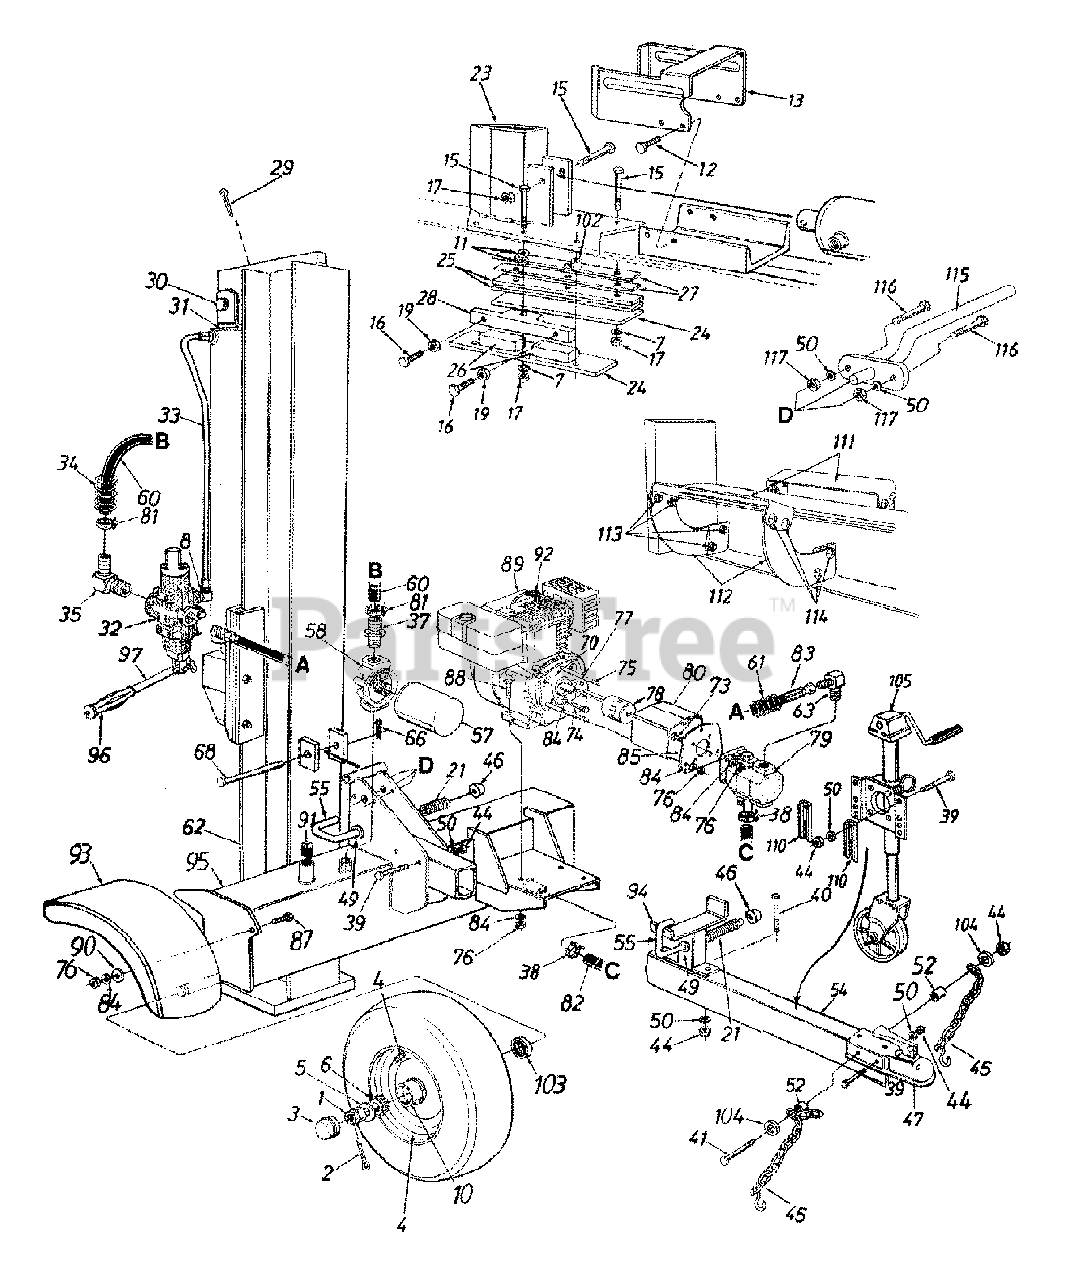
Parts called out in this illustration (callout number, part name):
1	Slotted Nut 3/4-16 Thd.
2	Cotter Pin 5/32" Dia.
3	Hub Cap
4	Wheel Ass'y. Comp.
5	Fl-Wash. .76" I.D. x 1.5" O.D.
6	Bearing Cone
7	L-Wash. 1/2" I.D.
8	90° Solid Male Adapter
10	Bearing Cup
11	Fl-Wash. .531" I.D. x .94" O.D.
12	Hex Cap Scr. 3/8-16 x 1" Lg.
15	Hex Bolt 1/2-20 x 2.75" Lg. (Grade 8)
16	Hex Bolt 3/8-24 x 1.5" Lg.
17	Hex L-Nut 1/2-20 Thd.
19	Hex Jam Nut 3/8-24 Thd. (Grade 5)
21	Comp. Spring 4" Lg.
23	Wedge Ass'y.
27	Adjustable Gib Shim
29	Cotter Pin
30	Cylinder Mounting Pin
31	Hydraulic Cylinder
31	Kit Seal 5.0" for Fisher Hydraulics cylinder 718-0313
31	Kit Seal 5.0" for Best Metals cylinder 718-0313
31	Kit Seal 5.0" for XINGHUI cylinder 718-0313A
31	Kit Seal 5.0" for ENERGY cylinder 718-0313A
32	Control Valve
33	Metal Pressure Tube
34	Hose Guard
35	Return Elbow
37	3/4" Hose Barb.
38	Hose Clamp 1.5" O.D.
39	Hex Bolt 3/8-16 x 3" Lg. (Grade 8)
40	Hex Bolt 3/8-16 x 4.75" Lg.
41	Hex Bolt 3/8-16 x 4.25" Lg.
44	Hex Nut 3/8-16 Thd.
45	Chain-Tow Hitch
46	Push Cap
47	Hitch Coupler
49	Fl-Wash. .635" I.D. x .93" O.D.
50	L-Wash. 3/8" I.D.
52	Spacer .445" Lg.
54	Tongue Tube
55	Locking Rod
57	Filter Element
58	Filter Head
60	Return Hose 3/4" I.D. x 44" Lg.
61	Hose Guard
62	Vertical Beam Weldment
63	90° Adapter (Male)
66	Cotter Pin 1/8" Dia.
68	Hinge Pin 1/2 x 4.8" Lg.
70	Front Coupling Support Brkt.
73	Hex Bolt 5/16-24 x 1" Lg.
74	Hex Bolt 5/16-24 x .62" Lg.
75	Hex Bolt 5/16-24 x 5.25" Lg.
76	Hex Nut 5/16-24 Thd.
77	Sq.-Key 1/4" x 2" Lg.
78	Flexible Coupling
79	Gear Pump
80	Coupling Shield
81	Hose Clamp 5/8"
82	Suction Hose 1" I.D.
83	High Pressure Hydraulic Hose
84	L-Wash. 5/16" I.D.
85	Rear Coupling Support Brkt.
87	Hex Bolt 5/16-24 x .75" Lg.
88	Hex Bolt 5/16-24 x 1.75" Lg.
89	Engine
90	Fl-Wash. .344" I.D. x .875" O.D.
91	L-Vent Pipe Plug
92	Spark Plug Boot
93	Fender
97	Control Handle
102	Spacer 1/2" I.D. x .86" Lg.
103	Bearing Seal Only
104	Fl-Wash. 3/8" I.D. x .87" O.D.
105	Jack Stand
112	Cradle Support Brkt.
113	Flanged Lock Nut 3/8-16 Thd.
114	Carriage Bolt 3/8-16 x 1" Lg.
117	Hex Nut 3/8-16 Thd.
